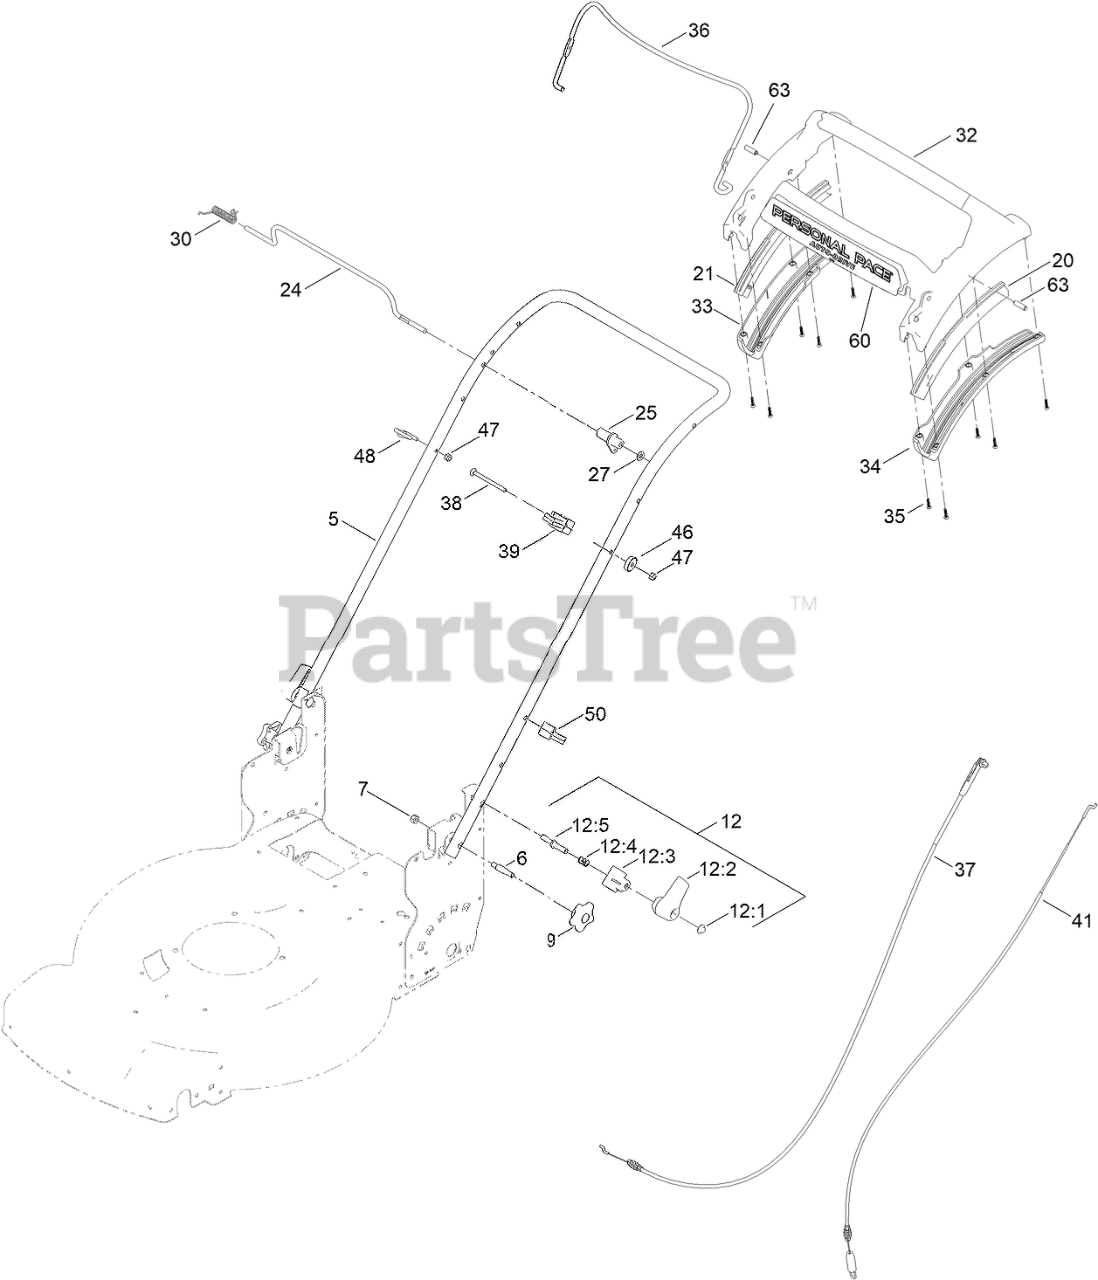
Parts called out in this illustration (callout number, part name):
5	HANDLE-CURVED
6	BOLT-SHOULDER, HANDLE
7	NUT-LOCK, NI
9	KNOB-HANDLE
12	QUICK RELEASE ASM
12:1	NUT-PUSH
12:2	LEVER-RELEASE
12:3	ANCHOR-SPRING
12:4	SPRING-COMPRESSION
12:5	ROD-RELEASE
20	GUIDE-CURVED, LH (RWD)
21	GUIDE-CURVED, RH (RWD)
24	ROD-CONTROL, TRACTION
25	LEVER-TRACTION, RWD
27	WASHER-PLAIN
30	SPRING-TORSION
32	HANDLE-PERSONAL PACE, CURVED
33	BOTTOM-HANDLE, RH
34	BOTTOM-HANDLE, LH
35	SCREW-PPH
36	BAIL-BRAKE
37	CABLE-BRAKE, PP BS
38	SCREW-CARR
39	ANCHOR-CABLE, RWD
41	CABLE-TRACTION, RWD (PP)
46	WASHER-CURVED
47	NUT-LOCK, NI
48	GUIDE-ROPE
50	GUIDE-CABLE
63	PIN-HANDLE, PP
